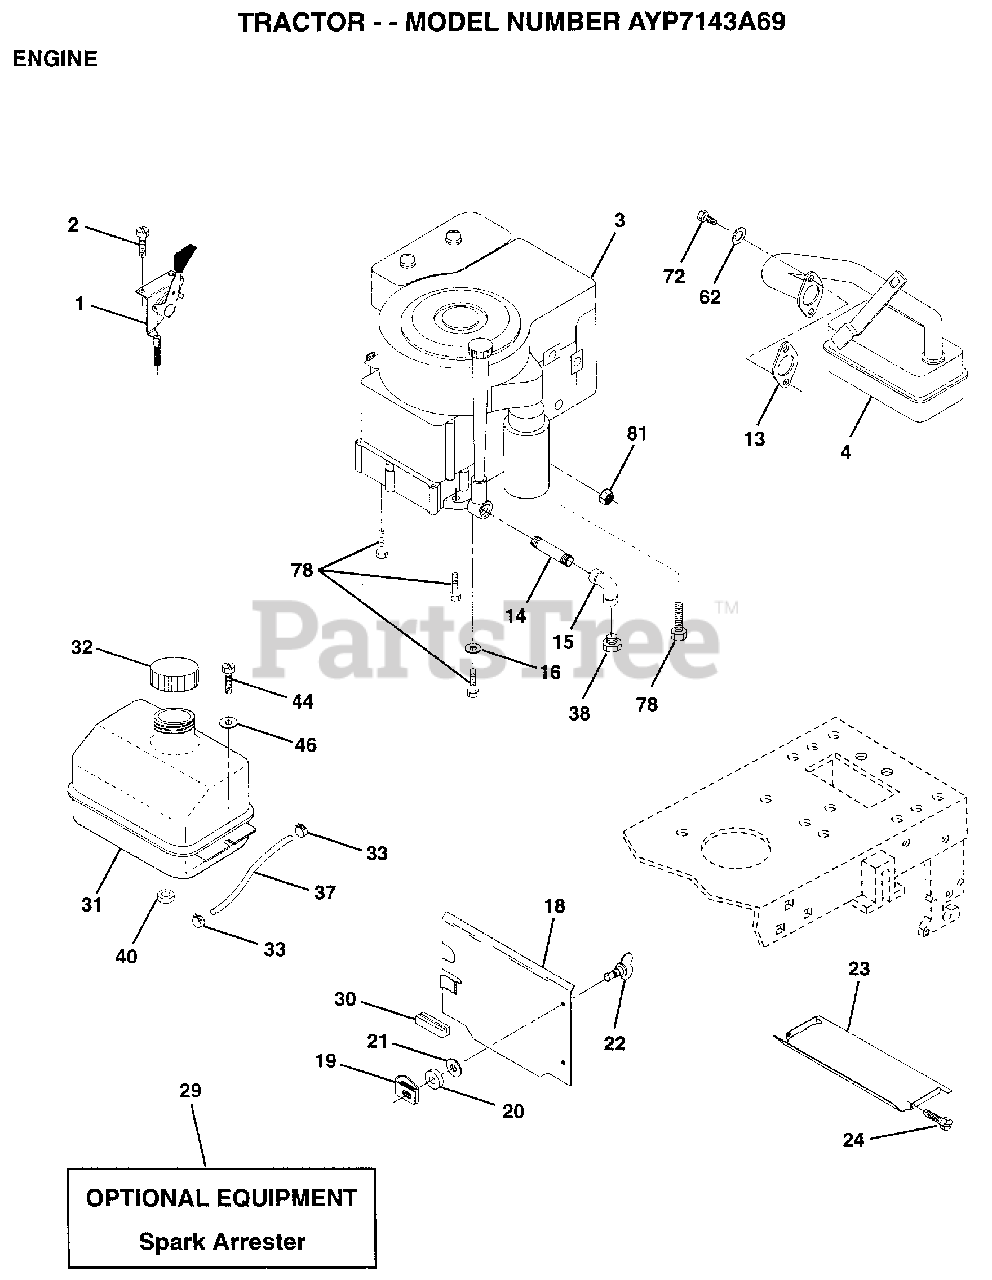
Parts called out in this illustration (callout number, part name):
1	CONTROL THROTTLE
2	SCREW LT
4	MUFFLER
13	GASKET ENG 1 313 LD TIN PLATED
14	PIPE NIPPLE
15	ELBOW
16	LOCKWASHER
18	SHIELD HEAT
19	RECEPTACLE LT
20	RETAINER LT
21	WASHER
22	STUD.1/4.TURN
23	HEAT SHIELD
24	SCREW
31	TANK.FUEL.LT.
32	CAP ASM FUEL
33	HOSE CLAMP
37	LINE FUEL
44	SCREW HEX CRT
46	WASHER
62	LOCKWASHER
72	SCREW
78	SCREW
81	NUT
